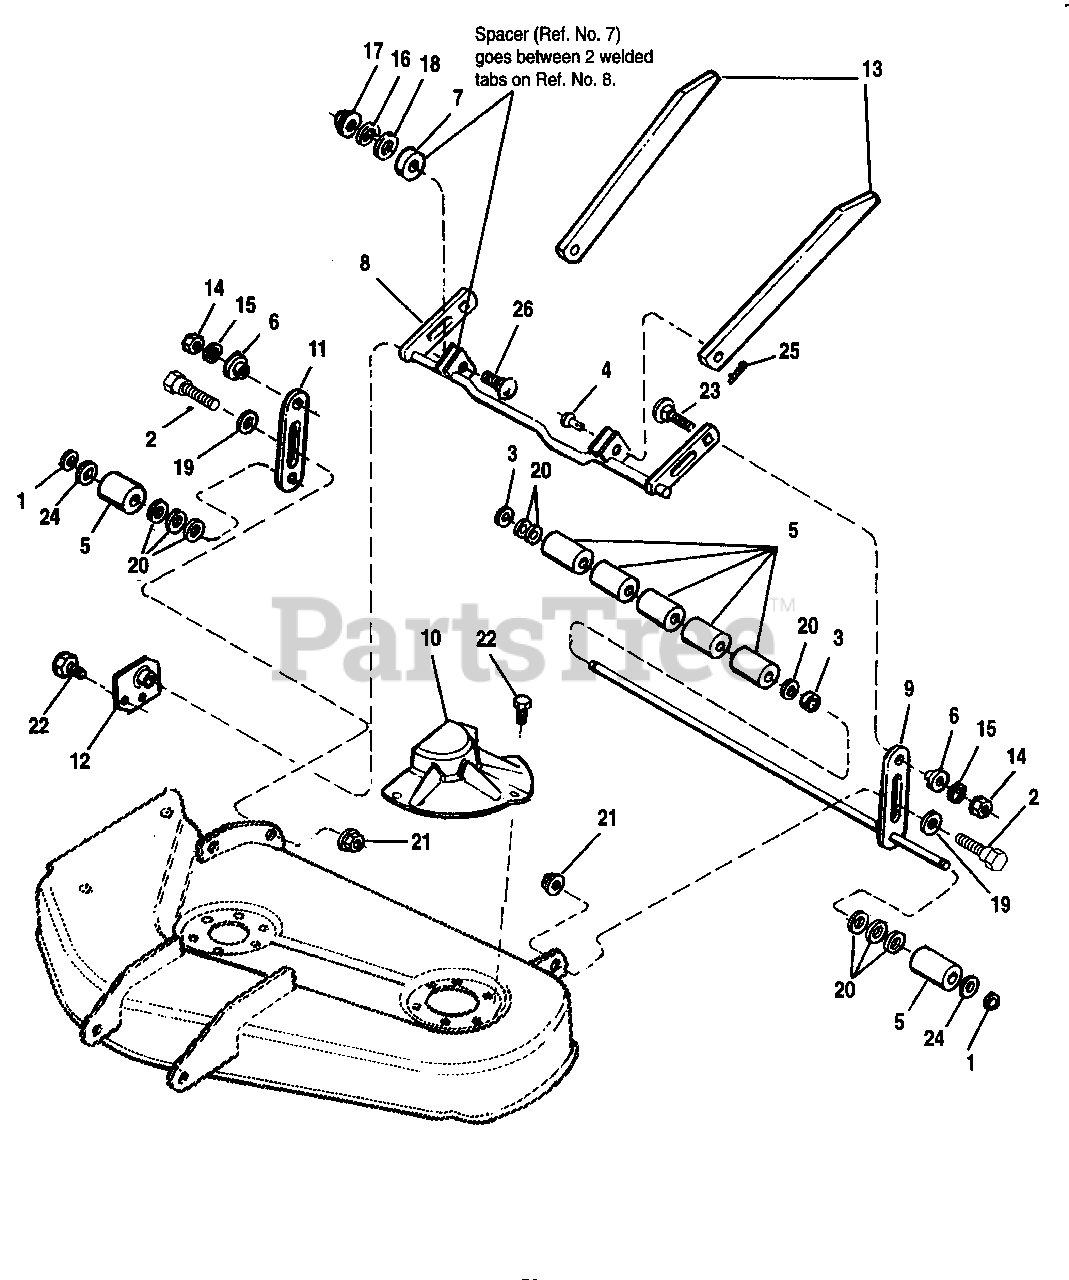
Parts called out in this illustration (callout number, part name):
1	RING, Retaining
2	BOLT, Shoulder, 3/8-16 X 1.34
3	SPACER, .66 ID
4	PIN, Locking
6	NUT, Hex Adjusting, .99 DIA .687
9	SHAFT ASSY., Roller
10	COVER, Arbor
11	BRACKET, Roller Bar, 34"
12	PLATE, Support, RH
13	BAR, Mower Transport
14	NUT, Hex, 3/8
15	LOCKWASHER, 3/8
16	LOCKWASHER, 5/16
17	NUT, Hex, 5/16-18
18	WASHER, Plain, 5/16
19	WASHER, Flat, 1/2
20	WASHER, 5/8
21	NUT, Flange Lock, 3/8
22	SCREW, Taptite, 5/16-18-5/8
23	CARRIAGE BOLT, 3/8-16 x 1-1/2
24	WASHER, Plain, 21/32 x 1-1/4 x 1/16
25	PIN, Retaining
26	CARRIAGE BOLT, 5/16-18 x 1-1/4
